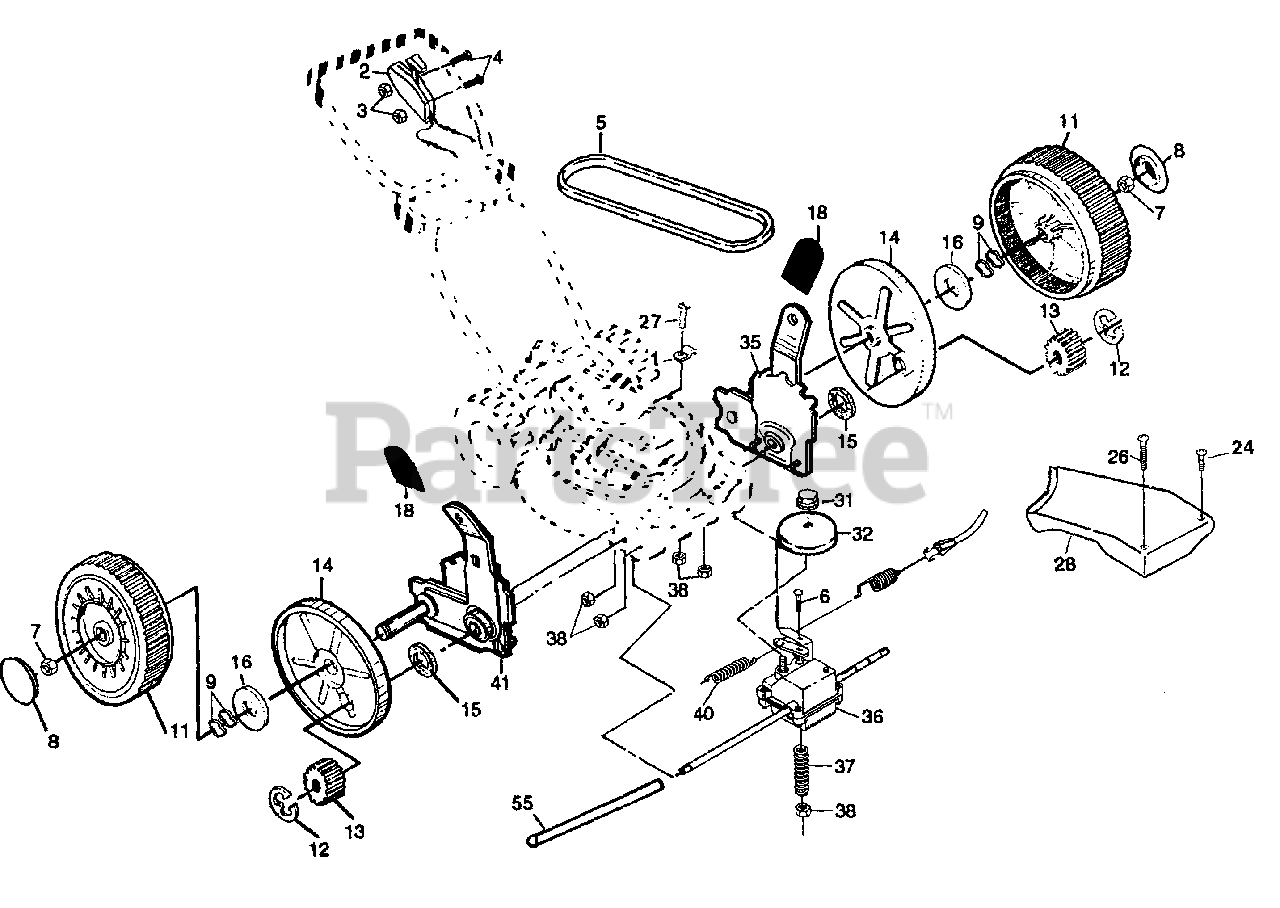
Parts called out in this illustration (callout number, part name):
1	Clip Guide
2	Dual Drive Control
3	Locknut #10-24
4	Pan Head Machine Screw #10-24 x 2
5	V-Belt
6	Carriage Bolt 1/4-20 x 2-3/4
7	Nut
9	Wave Washer
11	Wheel & Tire Assembly
14	Dust Cover
15	Felt Washer
16	Washer 1/2 x 1-1/2 x .134
18	Selector Knob
24	Pan Head Tapping Screw #10-24 x 1-3/4
26	Pan Head Tapping Screw #10-24 x 2-3/4
27	Hex Washer Head Screw #10-24 x 3/4
28	Drive Cover
31	Hex Flange Nut
32	Drive Pulley
35	Wheel Adjuster Assembly (Left)
36	Gear Case Assembly
38	Hex Locknut 1/4-20
41	Wheel Adjuster Assembly (Right)
55	Driveshaft Cover
